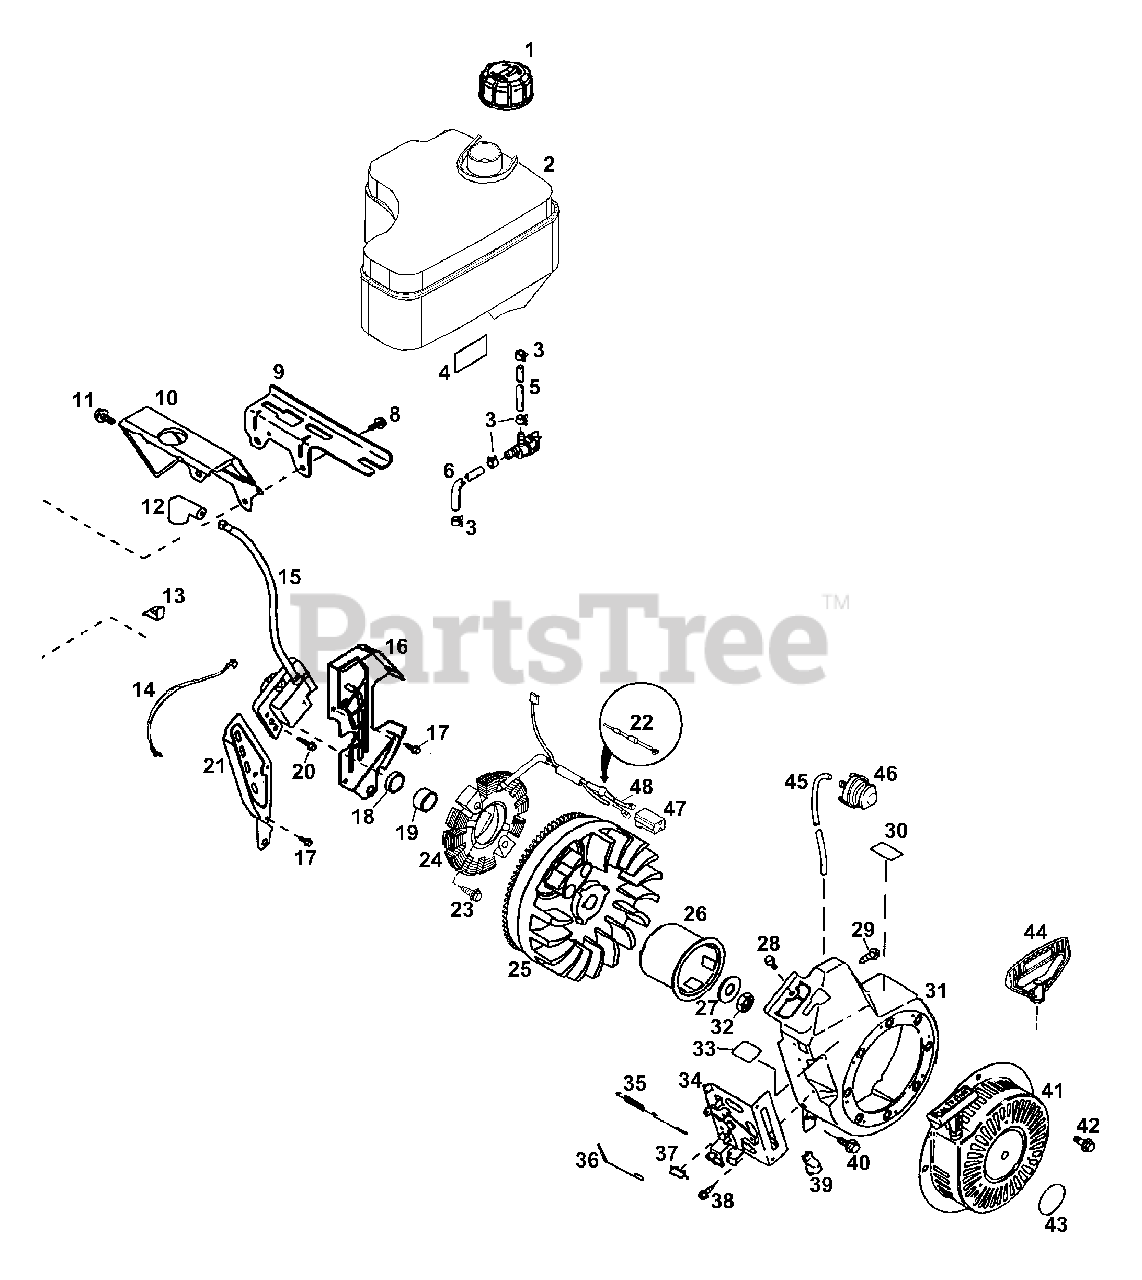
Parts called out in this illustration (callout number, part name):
1	Fuel Cap
2	Fuel Tank
3	Fuel Line Clamp
4	Instruction Decal
5	Fuel Line
6	Fuel Line
8	Screw, 1/4-20 x 7/8"
9	Fuel Tank Bracket
10	Blower Housing Extension
11	Screw, 10-24 x 9/16"
12	Spark Plug Cover
13	Wire Clip
14	Ground Wire
15	Solid State Ignition
16	Air Baffle (Right)
17	Screw, 10-24 x 9/16"
20	Screw, Torx T-15, 15/16"
21	Air Baffle (Left)
23	Screw, 1/4-20 x 3/4"
24	Alternator Coil
26	Starter Cup
27	Bell Washer
28	Screw, 1/4-20 x 31/64"
29	Screw, 10-32 x 1/2"
30	Lube Decal
31	Blower Housing
32	Flywheel Nut
33	Control Decal
34	Control Bracket
35	Extension Spring
36	Governor Link
38	Screw, 10-32 x 1/2"
39	Control Knob
40	Screw, 1/4-20 x 31/64"
41	Rewind Starter
42	Screw, 1/4-20 x 31/64"
43	Starter Decal
44	Mitten Grip Starter Handle
45	Primer Line
46	Primer Assembly
